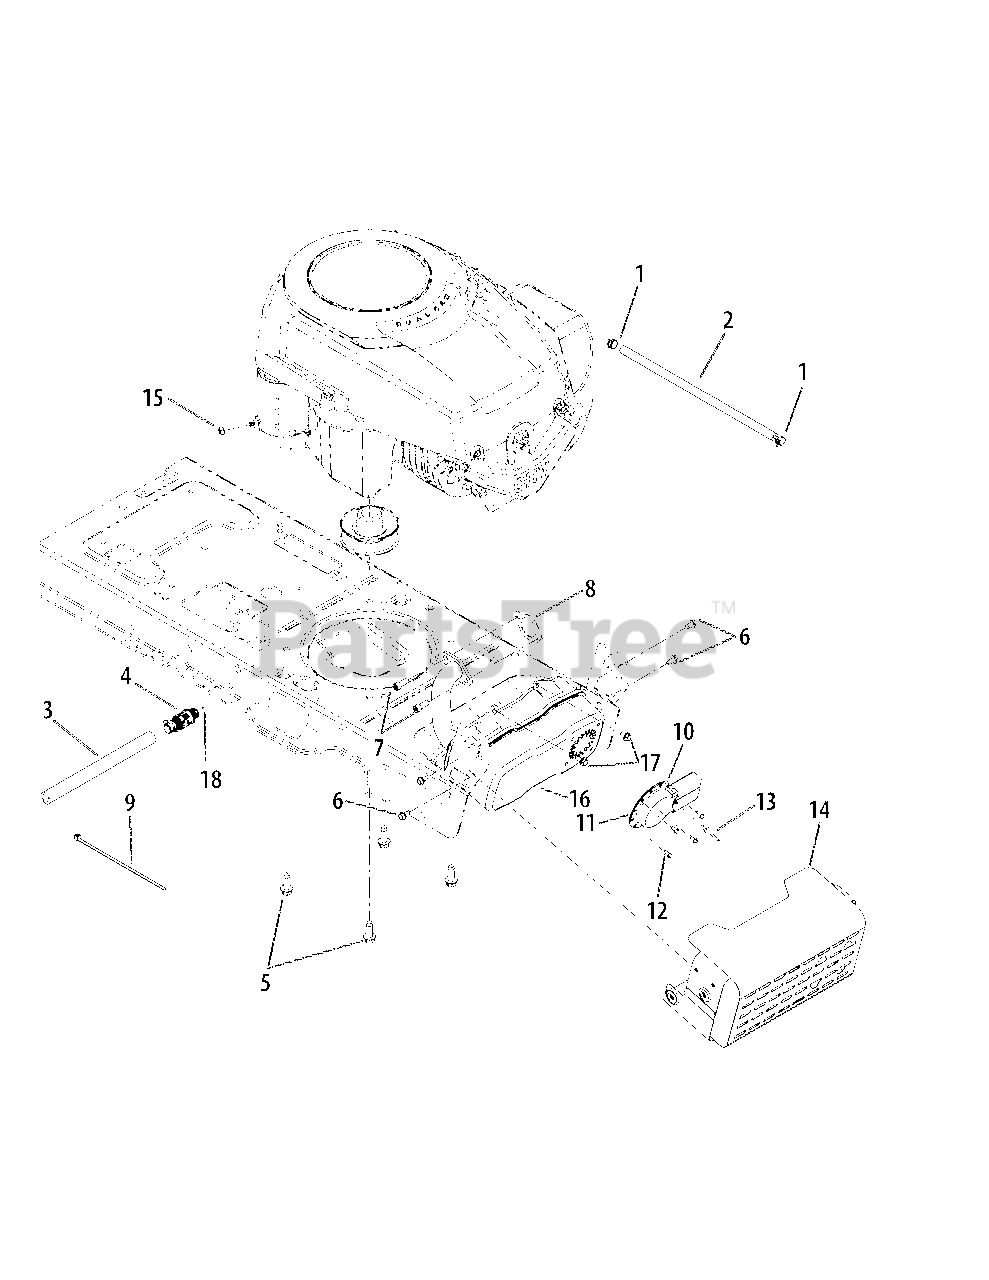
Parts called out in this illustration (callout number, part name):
3	Oil Drain Hose
5	TT Screw 3/8-16 x 1.00
6	Hex Wash S-Tapp Scr 1/4-20 x .50
7	Scr. 5/16-18 x .75
8	Exhaust Gasket
10	Muffler Deflector
11	Long Muffler Deflector
12	Hex AB Scr #8-18 x .50
14	Muffler Shield Assembly
15	Hex Sems Nut 1/4-20
16	Muffler
17	Hex Washer Screw 1/4-20 x .625
